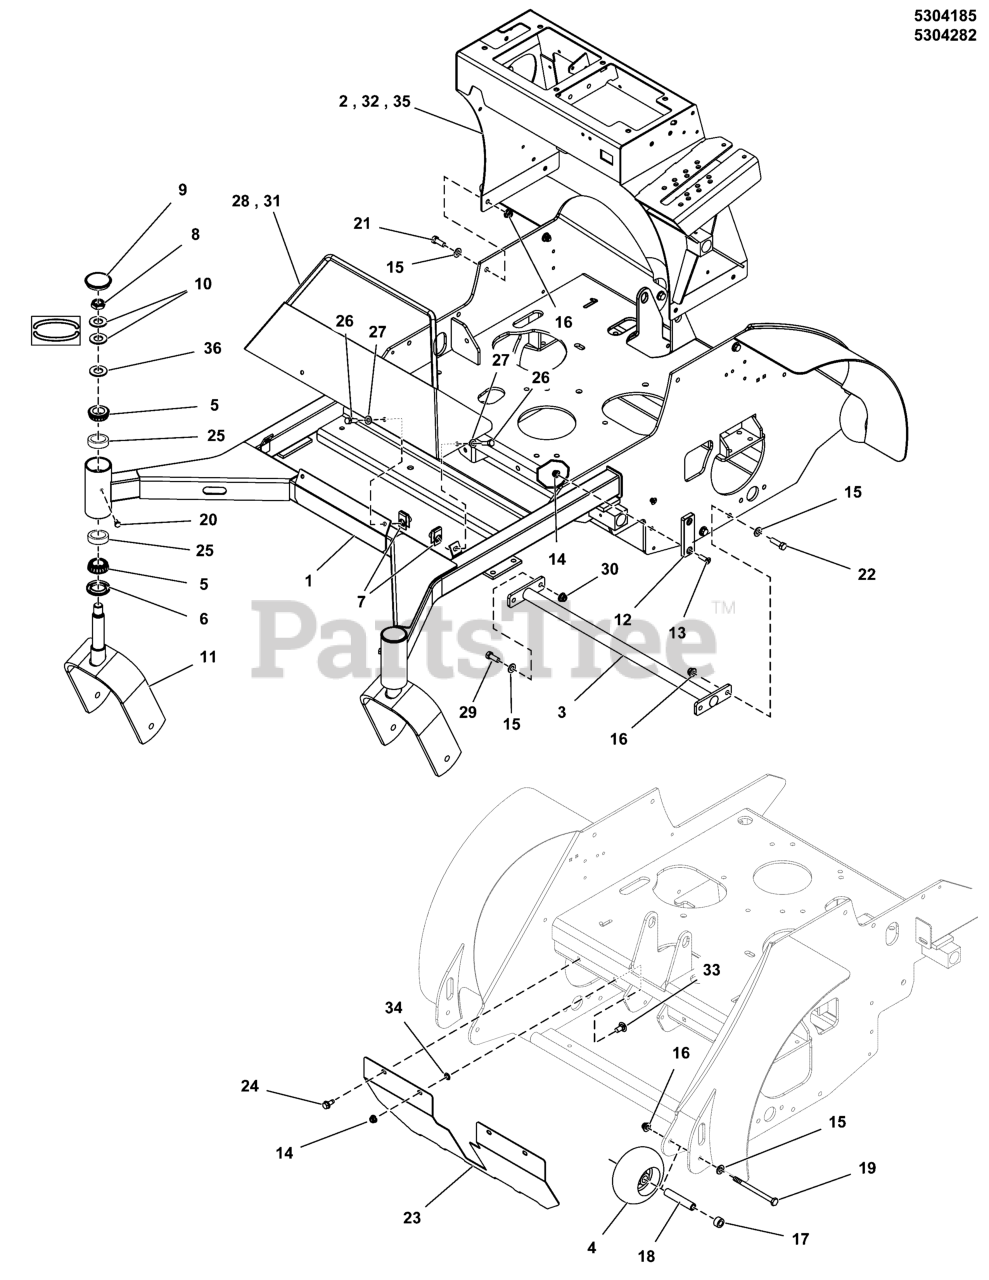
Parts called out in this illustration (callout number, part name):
1	FRAME
2	WELD, TOWER INSTRUMENT, CONTROL - RED
3	WELD, CENTER CROSS BRACE - BLK
4	GAUGE WHEEL-2.70
4	WHEEL, ANTI SCALP, 5"
5	BEARING, TAPERED ROLLER, 1"
6	SEAL, GREASE
7	BODY CLIP, 5/16-18-7GA MATERIAL
8	NUT, 3/4-16, HEX JAM NYLON LOCK
9	CAP, GREASE, LOW PROFILE
10	WASHER, BELLEVILLE - 1.500 X .755
11	WELD, CASTER YOKE - RED MODEL
11	WELD, CASTER YOKE - RED
12	PAD, FRICTION, .375 X 1.25 X 4.00
13	SCREW, 5/16-18 X 1, PHILLIPS HD, BZ
14	NUT, 5/16-18 HEX NYLOCK FLANGE NUT
15	WASHER, 3/8 SAE
16	NUT, 3/8 - 16 HEX NYLOCK FLANGE
17	SPACER, .64 X 1.13 X .63, CZ
18	SPACER, .38 X .63 X 3.25, YZ
18	SPACER, .38 X .63 X 3.38, CZ
19	BOLT, 3/8-16 X 4-1/2" GD5 CZ
20	BOLT, 1/4-28 X 1/2, GD5 YZ
21	BOLT, 3/8-16 X 1" GD5 CZ
22	BOLT, 3/8-16 X 1-1/4" GD5 CZ
23	PLATE, HEAT SHIELD, STAND ON - RED
24	BOLT, 5/16-18 X 3/4", SELF-TAPPING
25	CUP, BEARING (SV)
26	BOLT, 5/16-18 X 1" GRD5 YZ
27	WASHER, 5/16" SAE
28	WELD, FRONT FRAME GUARD, SRSZ2 - RED
29	BOLT, 3/8-16 X 1-1/2" GD5 CZ
30	NUT, Hex, Side Lock, 3/8-16
31	WELD, FRONT GUARD, SRS Z2 61 - RED
32	WELD, CONTROL TOWER, Z2
33	BOLT, 5/16-18 X 3/4, CARRIAGE, GD5, CZ
34	5/16" PUSH-ON NUT RETAINER, STL, CZ
35	WELD, CONTROL TOWER, SRS Z2 - RED
36	WASHER, 3/4 SAE
